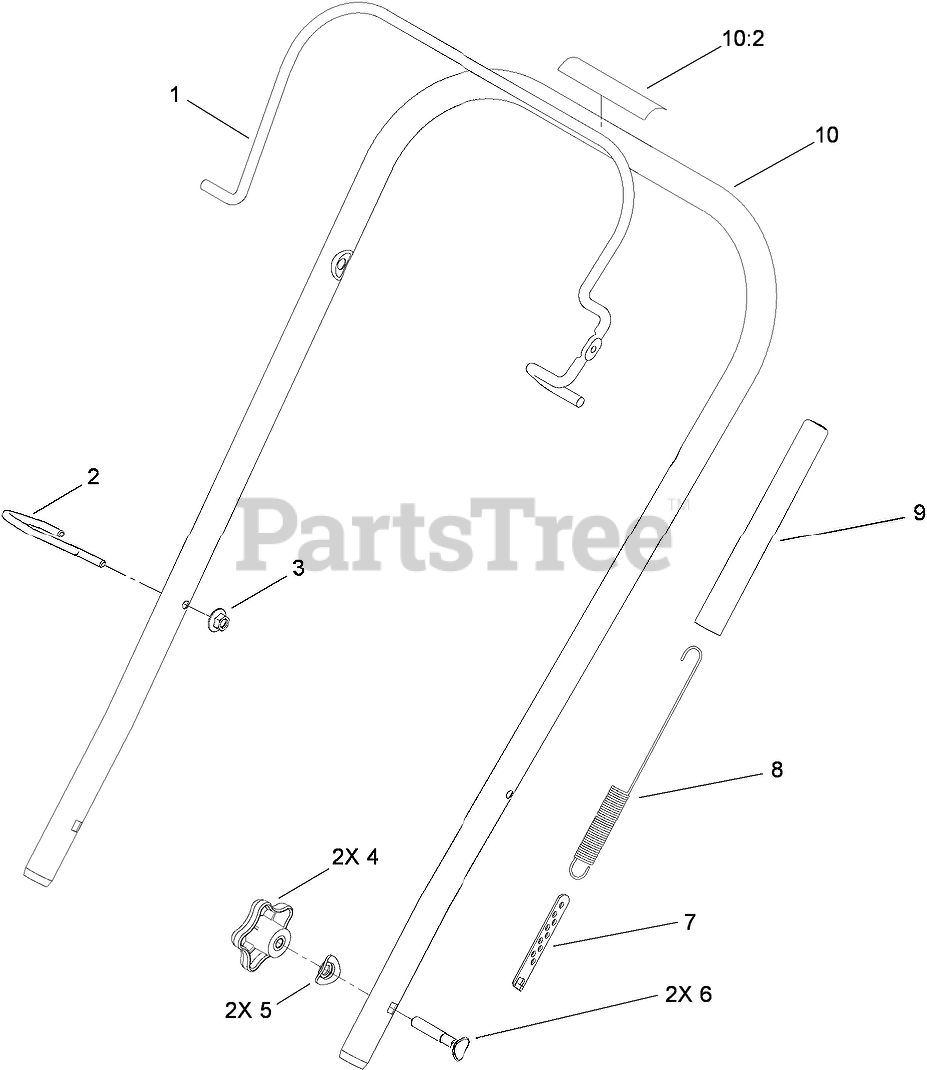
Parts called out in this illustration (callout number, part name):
1	BAIL-CLUTCH
2	GUIDE-ROPE, RECOIL
3	NUT-HEX FLG
4	KNOB-HANDLE
5	WASHER
6	SCREW-HANDLE
7	ADJUSTER-CABLE, CLUTCH
8	CLUTCH-SPRING
9	COVER-SPRING
10	UPPER HANDLE ASM
10:2	DECAL-SAFETY
